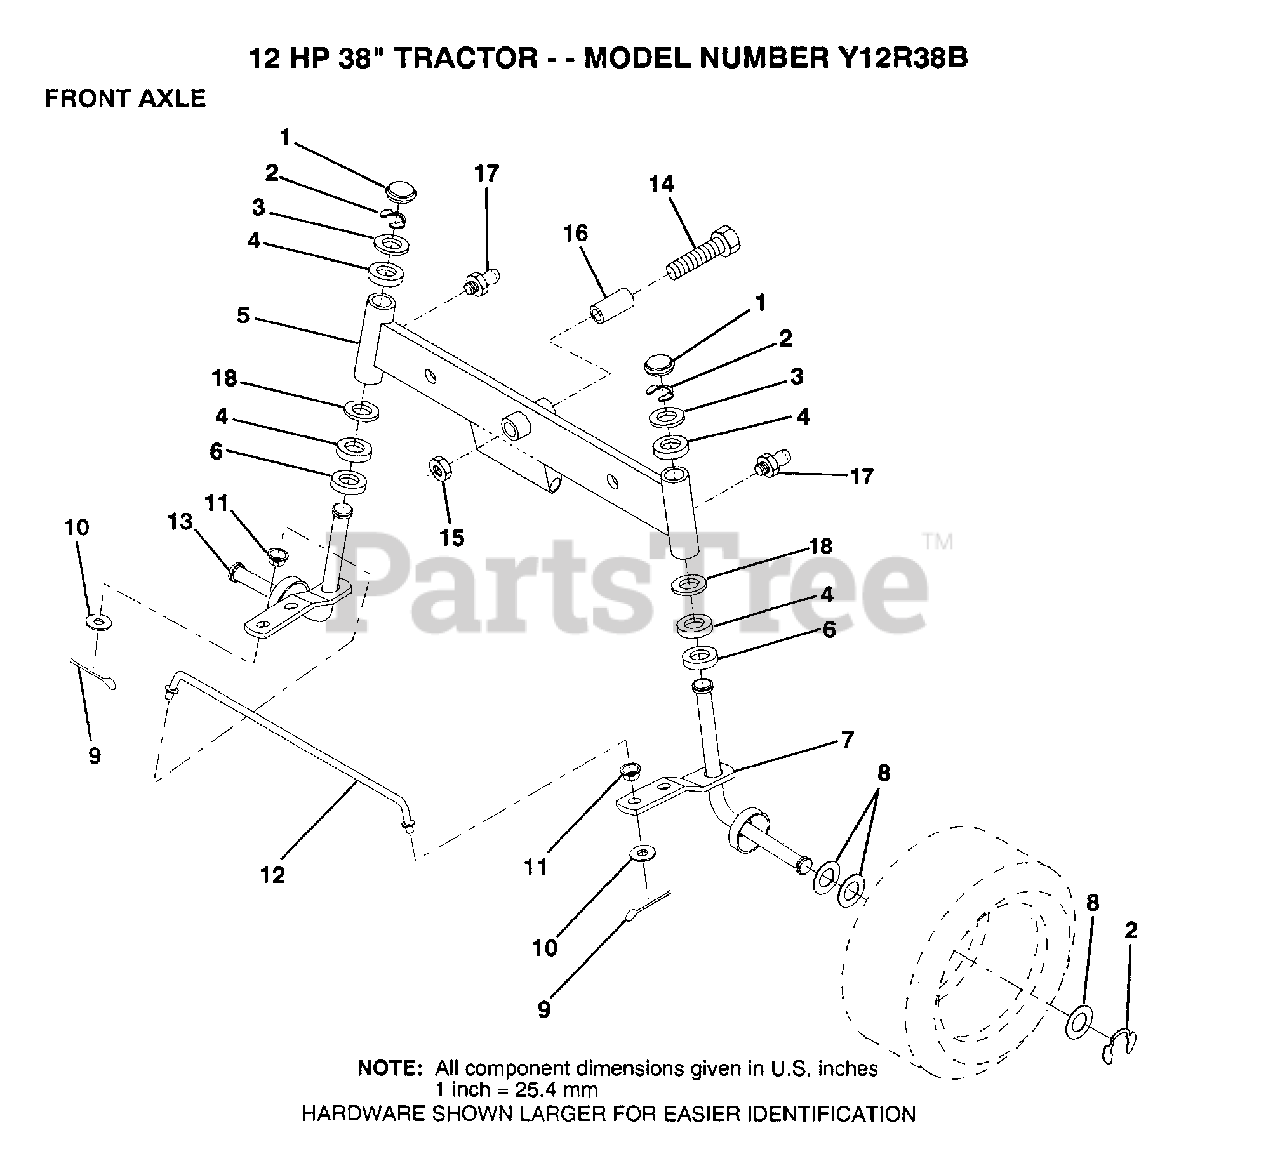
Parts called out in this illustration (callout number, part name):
1	CAP
2	RING
3	WASHER
4	COL. SRTG. BEAR.
6	WASHER .T
7	SPINDLE ASM RH
8	WASHER
9	COTTER PIN
10	WASHER
11	BUSHING.DRAGLINK
12	TIE ROD
13	SPINDLE ASM LH
14	BOLT HEX 5/8-11
15	"NUT-LOC,FLANGE LT"
16	BEARING
17	ZERK M
18	WASHER
